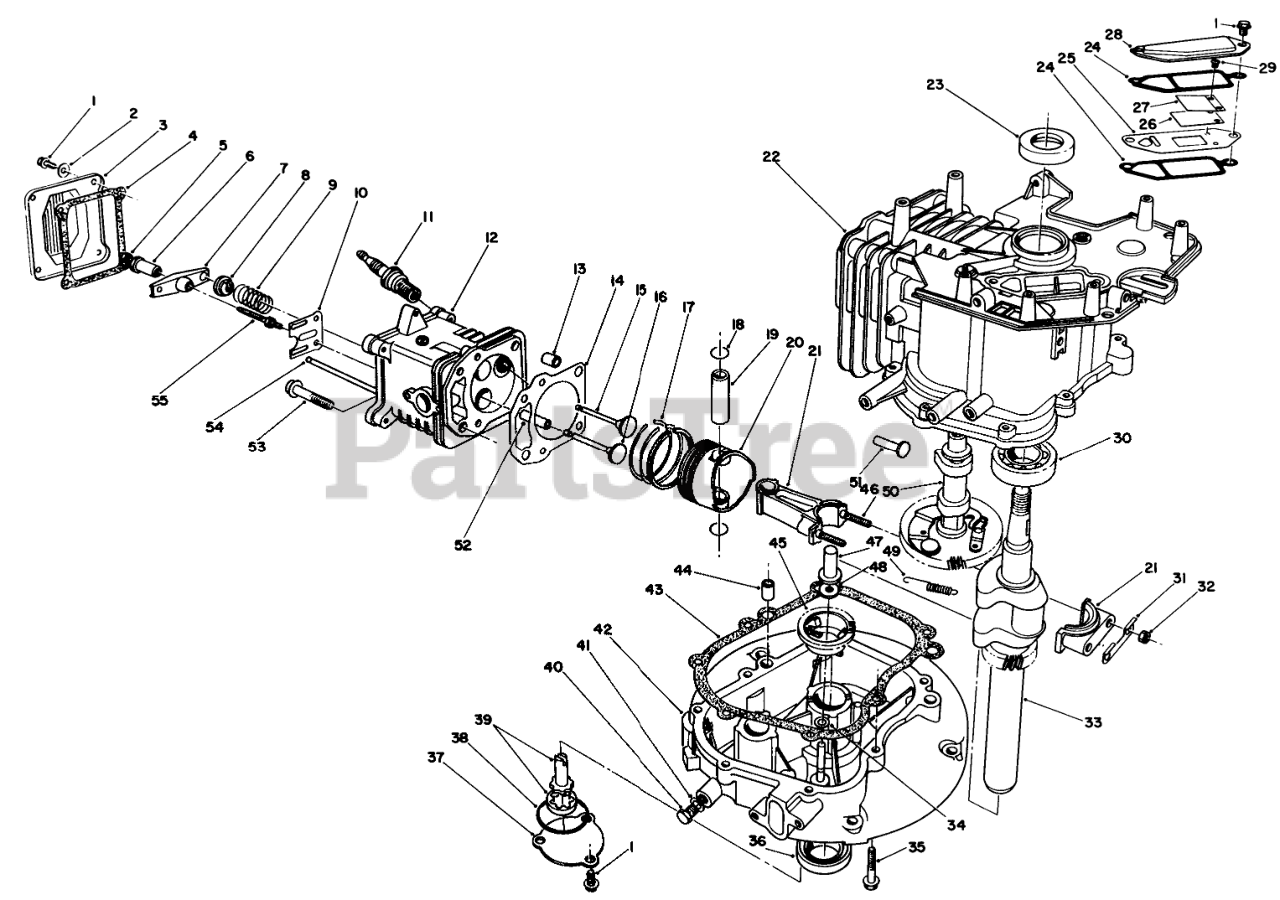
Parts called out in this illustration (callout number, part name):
2	WASHER
3	COVER
4	GASKET
6	PIVOT
8	RETAINER
9	SPRING
10	GUIDE
11	SPARK PLUG
12	Head-Cylinder (Incl. Ref. #52)
14	GASKET
15	VALVE-INTAKE
16	VALVE-EXHAUST
17	RING SET
18	CIRCLIP
20	PISTON
21	Connection Rod Assembly (Incl. Ref. #31, 32 & 46)
22	Block-Engine (Incl. Ref. #23, & 30)
24	GASKET
25	Plate-Breather
26	Valve-Reed
27	Retainer-Reed Valve
28	COVER
29	Screw-Reed Valve
30	BEARING
31	Plate-Lock
33	CRANKSHAFT
34	WASHER
37	COVER
38	O-RING
39	OIL PUMP
40	Plug-Oil Drain
41	GASKET
42	Crankcase
43	GASKET
45	GOVERNOR FLYWEIGHT ASM
47	PLUNGER
48	WASHER
49	SPRING
50	Camshaft Assy. (Incl. Ref. #49)
51	TAPPET
52	GUIDE
